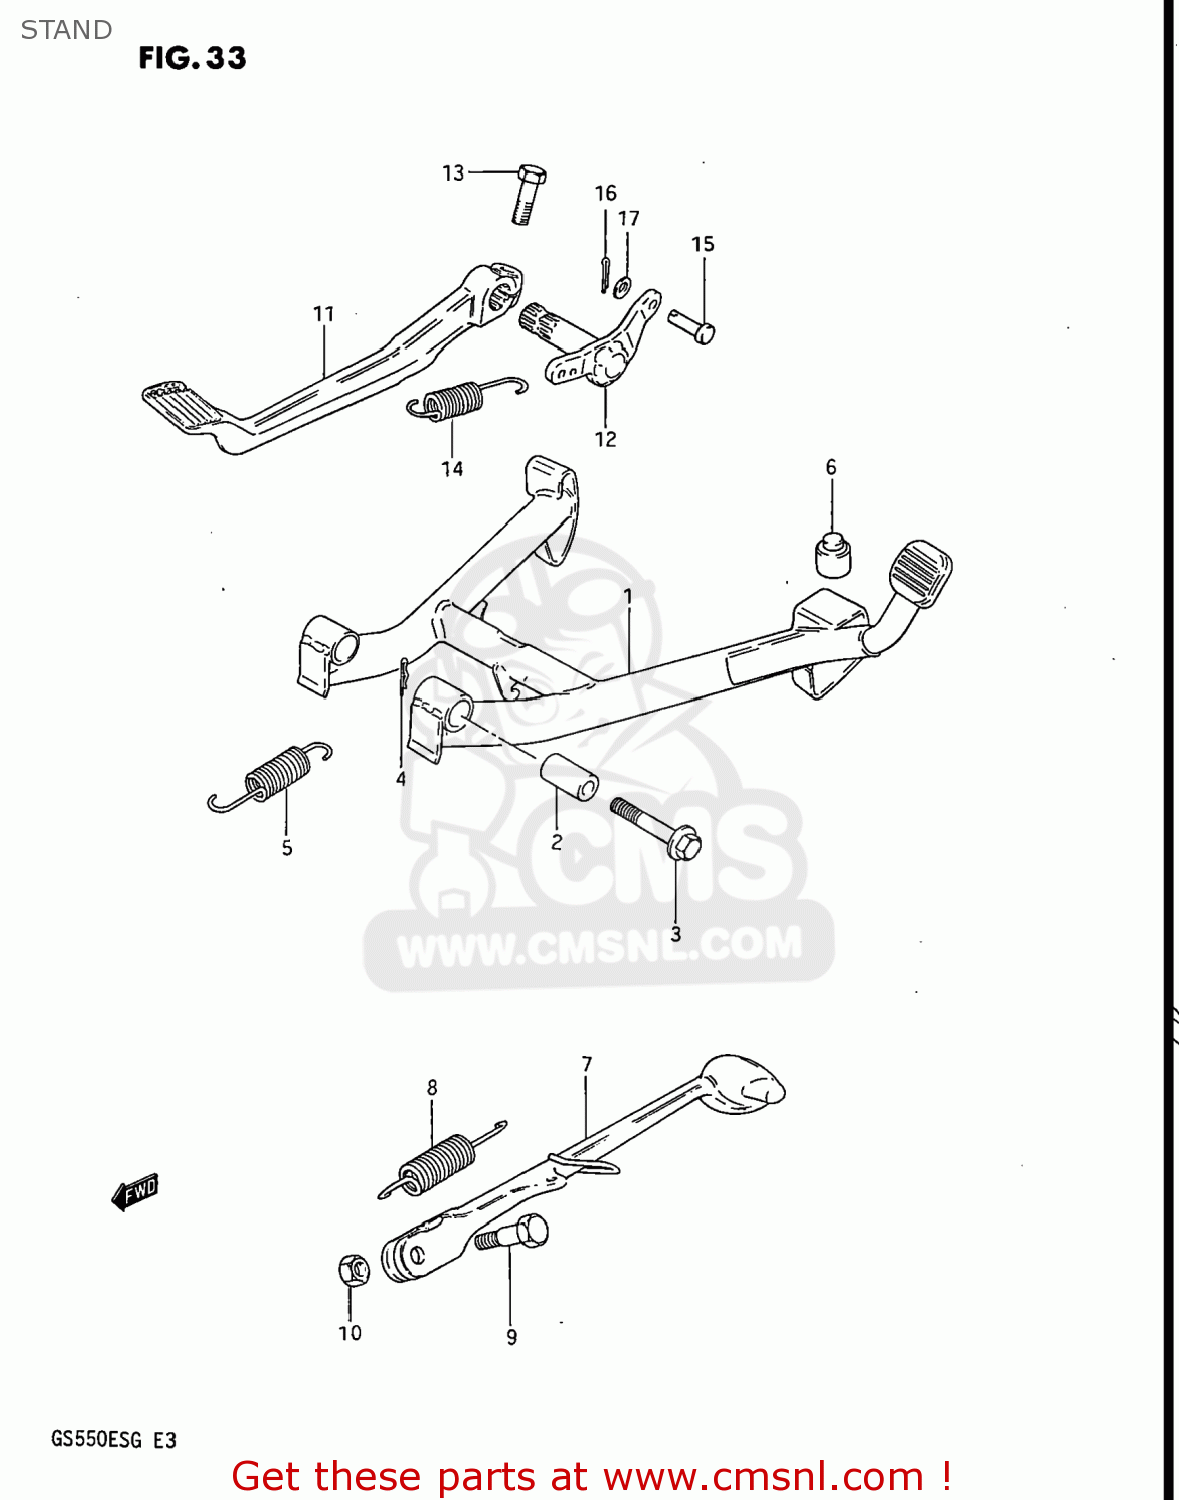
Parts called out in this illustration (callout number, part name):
1	STAND,CENTER
2	SPACER (10.5X16X31.8)
3	BOLT 10X50
4	CLIP
5	SPRING
6	CUSHION
7	STAND,SIDE
8	SPRING
9	BOLT L:30
10	NUTM10X1.25X8
11	PEDAL,BRAKE
12	ARM,BRAKE PEDAL ROD
13	BOLT
14	SPRING
15	PIN
16	PIN
17	WASHER
